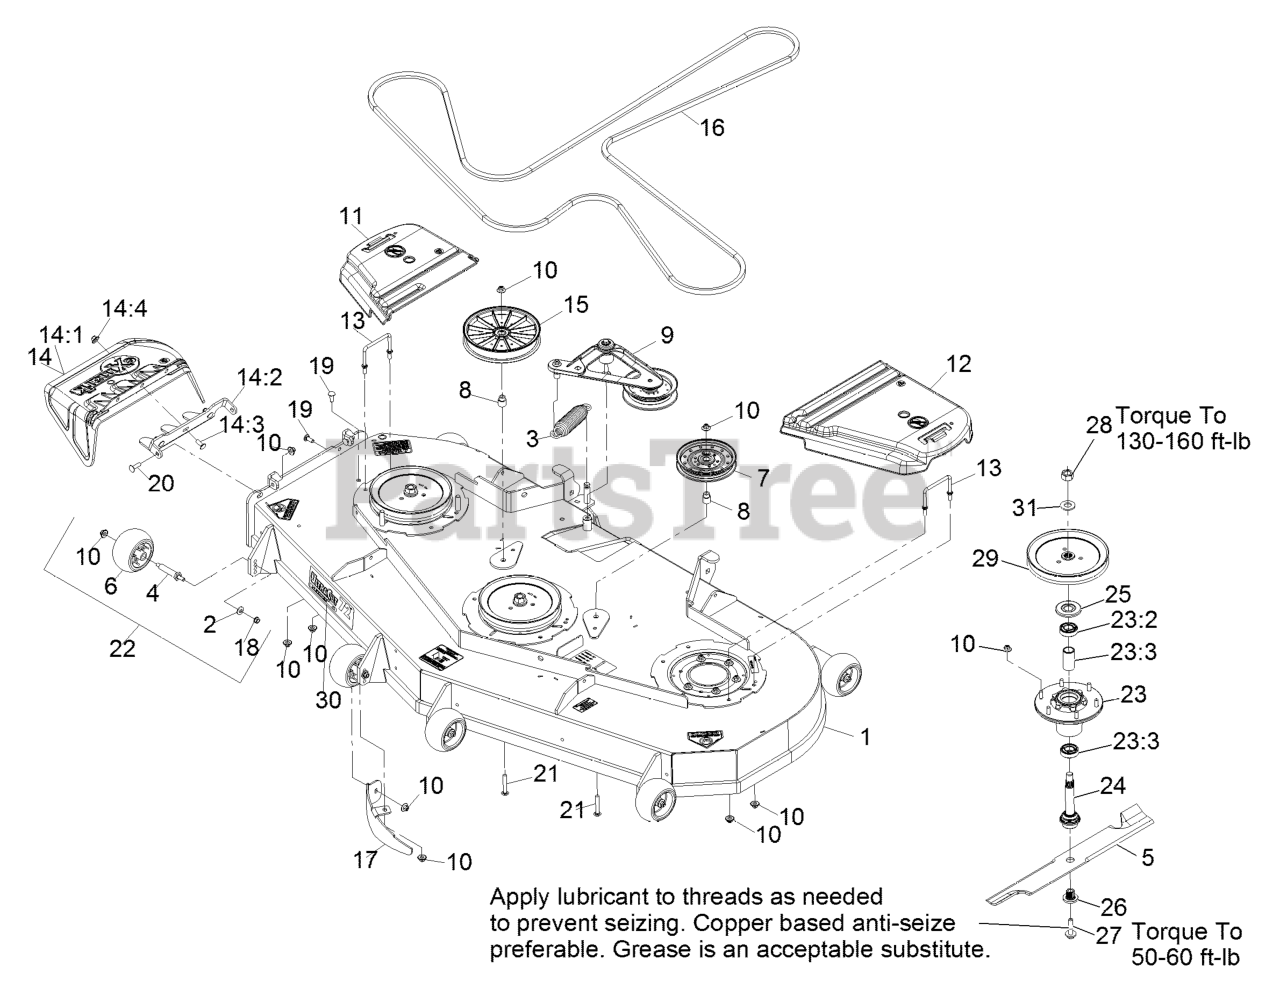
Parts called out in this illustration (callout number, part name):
1	ASM,DECK W/DECALS 724
2	WASHER-BELLEVILLE
3	SPRING-EXTENSION
6	ROLLER-SCALP, ANTI
8	BUSHING-IDLER
9	DECK IDLER ASM
10	Nut-Nyloc 3/8-16 Flg
11	COVER-BELT, RH
12	COVER-BELT, LH
13	WIREFORM-COVER
14	ASM,DISCHARGE CHUTE
14:1	CHUTE,DISCHARGE
14:2	BRACKET,DISCHARGE CHUTE
14:3	SCREW-CARR
14:4	Nut-Nyloc 3/8-16 Flg
15	PULLEY,IDLER 8"FLAT
16	BELT-V
17	BAFFLE-DOGLEG, LZ72
18	NUT-HHF, WHIZ
19	SCREW-CARR
20	Bolt-Carriage 3/8-16 X 1 1/4
21	SCREW-CARR
23	ASM-CUTTER HSG WITH BEARINGS
23:2	BEARING-BALL
23:3	SPACER-BEARING
24	ASM-SPINDLE AND SEAL
25	GUARD,BEARING TOP .989
26	BUSHING,SPLINED
27	SCREW,SEMS 1/2-20 X 2.19
28	NUT-HEX
29	SHEAVE,BLADE DRIVE 8.74
30	DECAL,ULTRACUT 72 SERIES
